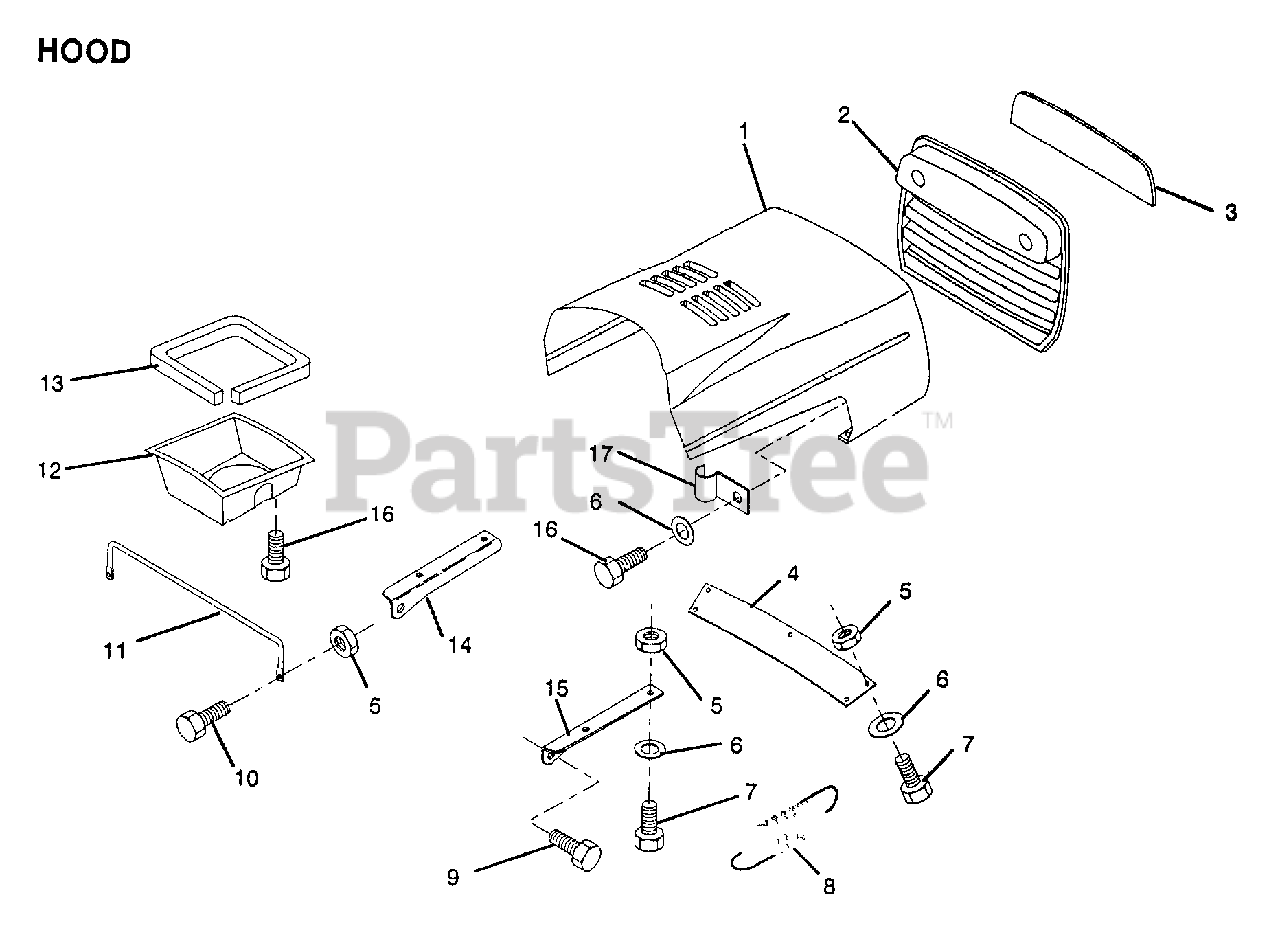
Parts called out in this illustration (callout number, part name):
2	GRILL
3	LENS
5	NUT
6	WASHER
7	BOLT
8	EXT SPRING
11	"BRACE,HOOD"
12	"DUCT,AIR"
13	FOAM STRIP LT
14	BRKT HOOD LH
15	BRKT HOOD RH
17	CLIP T
